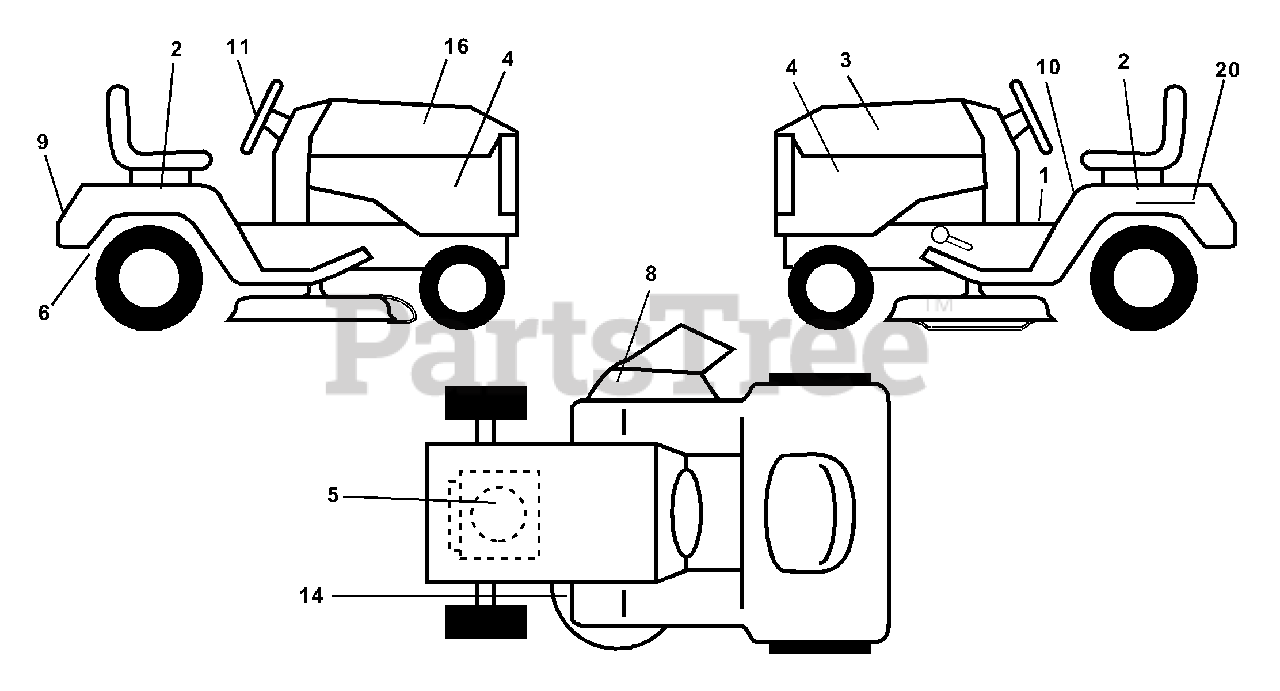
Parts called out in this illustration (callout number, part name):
1	Decal Oper
2	Decal Fender Auto
3	Decal Hood LH
4	Decal Side Panel Logo
5	Decal HP Engine
6	Decal By Pass Lt Hydro
8	Decal Mower Warn Keep Hand Away
9	Decal Fender Logo
10	Decal Fender Danger E/F
11	Decal Ins Strg Whl
14	Decal V-Belt Schematic
16	Decal Hood Rh
20	Decal Bat Dan/Psn
